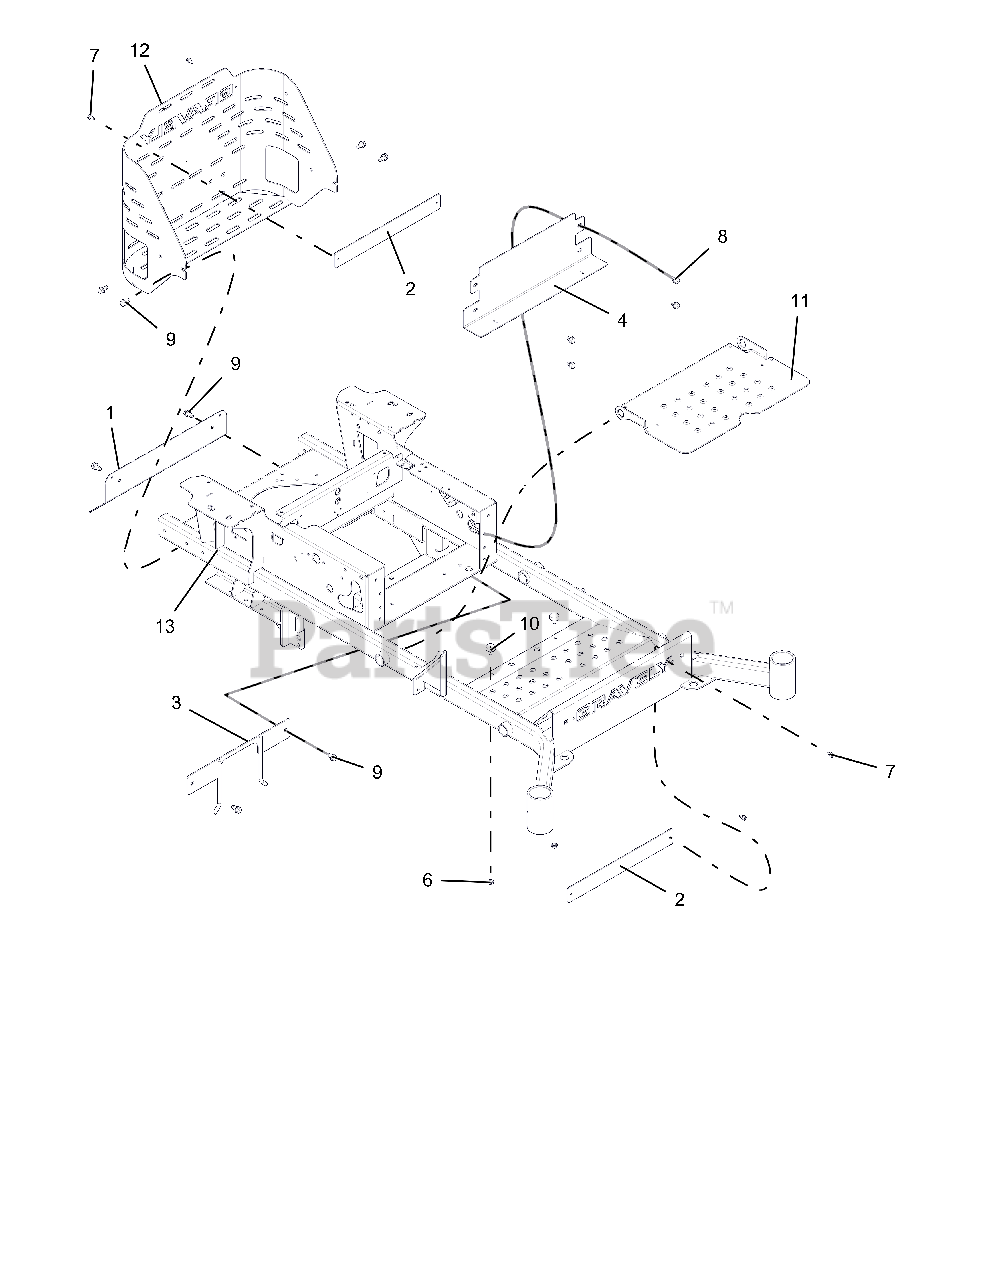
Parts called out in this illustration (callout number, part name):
1	SHIELD, MUFFLER HEAT
2	PLATE, BUMPER 2.00 x 16.50 - BLK
3	WLDMT, PTO BELT FINGER-BLACK
4	PLATE, PT/PT100 KICK-RED
5	BUMPER, PRO-TURN REAR
6	@NUT-SPNLK-FLG .312-18 YWZC
7	SCR-TAP .25-20X.50 HWH TR YWZ
8	SCR-TAP .38-16X.50 HWH TR YWZ
9	SCR-TAP .38-16X.75 HWH TR YWZ
10	BUMPER, RUBBER
11	FOOT, PLATE W/SAFETY DECALS
12	REAR BUMPER W/SAFETY DECALS
13	60" MAIN FRAME W/SAFETY DECALS
